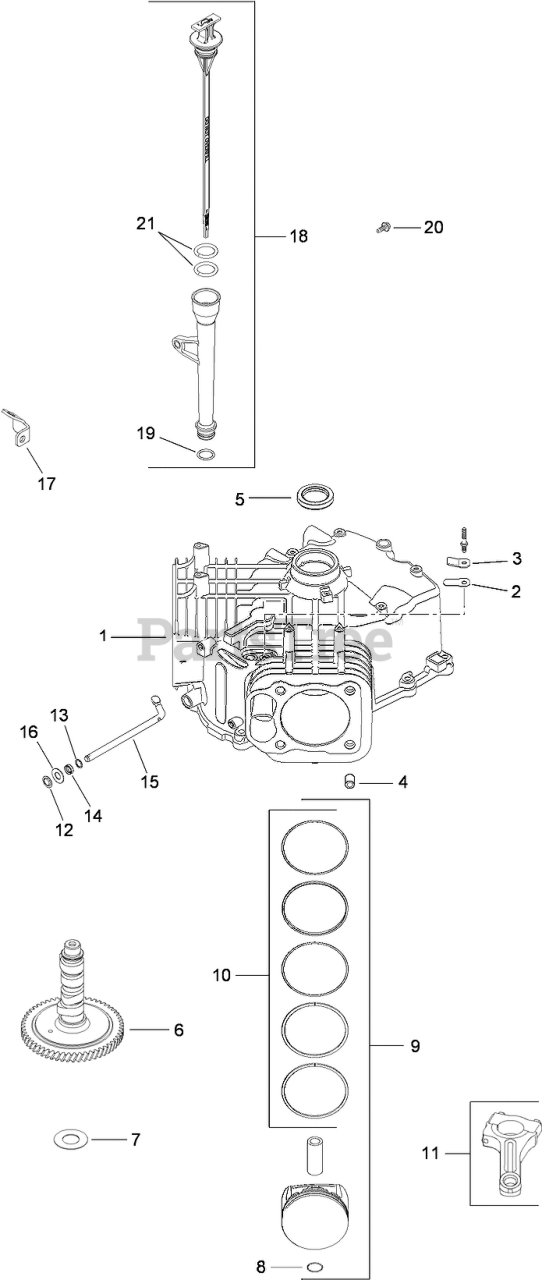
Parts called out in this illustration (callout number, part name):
1	SHORTBLOCK (SV710-740)
2	REED-BREATHER
3	RETAINER-REED, BREATHER
4	PIN-LOCATING
5	SEAL-OIL (HELIX LIP)
6	CAMSHAFT KIT
7	SHIM-CAMSHAFT (WHITE .028)
7	SHIM-CAMSHAFT (BLUE .03)
7	SHIM-CAMSHAFT (RED .032)
7	SHIM-CAMSHAFT (YELLOW .034)
7	SHIM-CAMSHAFT (GREEN .036)
7	SHIM-CAMSHAFT (GRAY .038)
7	SHIM-CAMSHAFT (BLACK .04)
8	RETAINER-PIN, PISTON
9	PISTON W/RING SET (STD)
9	PISTON W/RING SET (.25)
10	PISTON RING SET (STD)
10	PISTON RING SET (.25)
11	ROD-CONNECTING (STD)
12	RETAINER-RING
13	WASHER-FLAT (11/32)
14	SEAL-CROSS SHAFT, GOVERNOR
15	SHAFT-CROSS, GOVERNOR
16	WASHER-FLAT (9MM)
17	BRACKET-TUBE, OIL FILL
18	DIPSTICK AND TUBE ASM
19	O-RING (LOWER OIL FILL TUBE)
20	SCREW-FLG, THD FRM (M5X0.8X13)
21	O-Ring (Dipstick)
